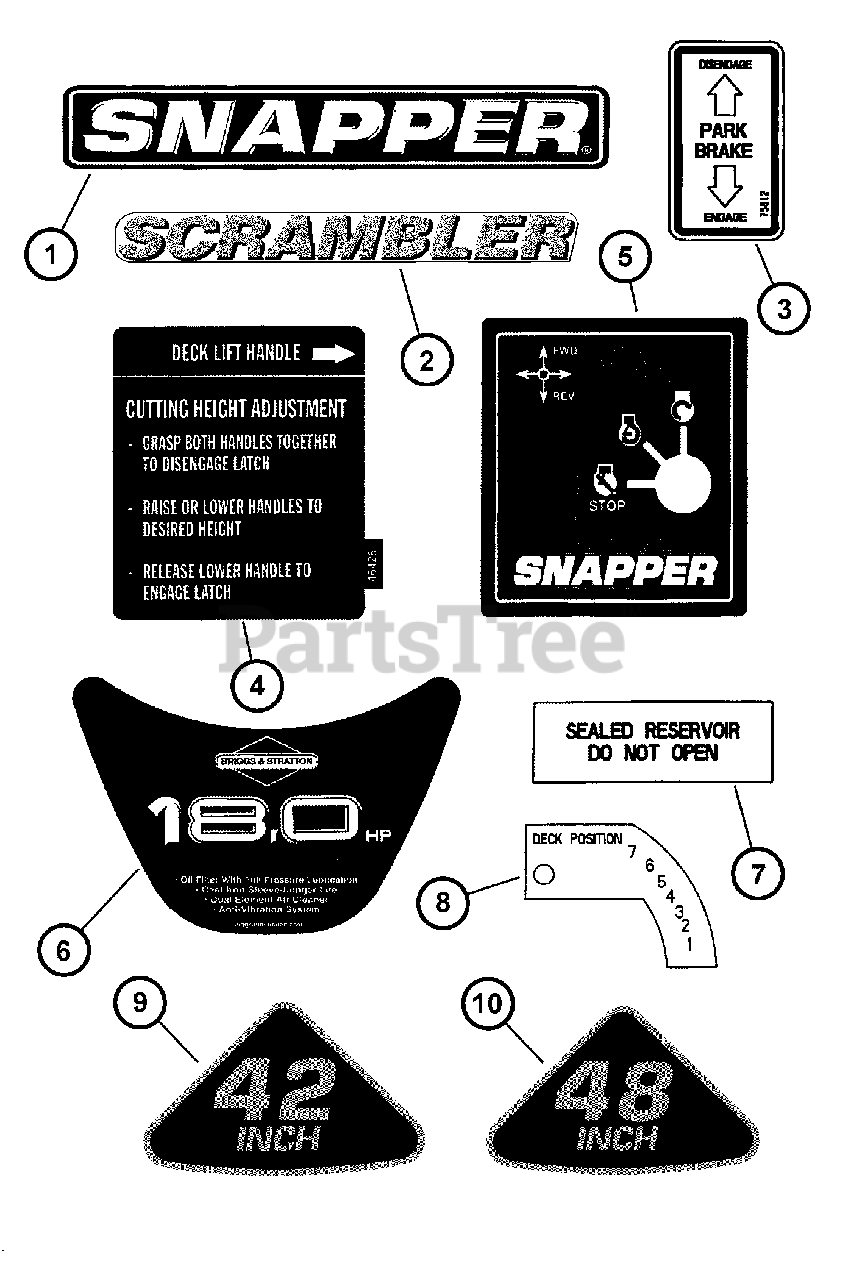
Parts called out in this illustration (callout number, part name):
1	DECAL, SNAPPER
2	DECAL, SCRAMBLER
3	DECAL, Park Brake
4	DECAL, Deck Height
5	DECAL, Ignition Switch
6	DECAL, Engine, 18 HP OHV B&S
7	DECAL, Hydro Reservoir
8	DECAL, Deck Position
9	DECAL, 42" Deck
10	DECAL, 48" Deck
